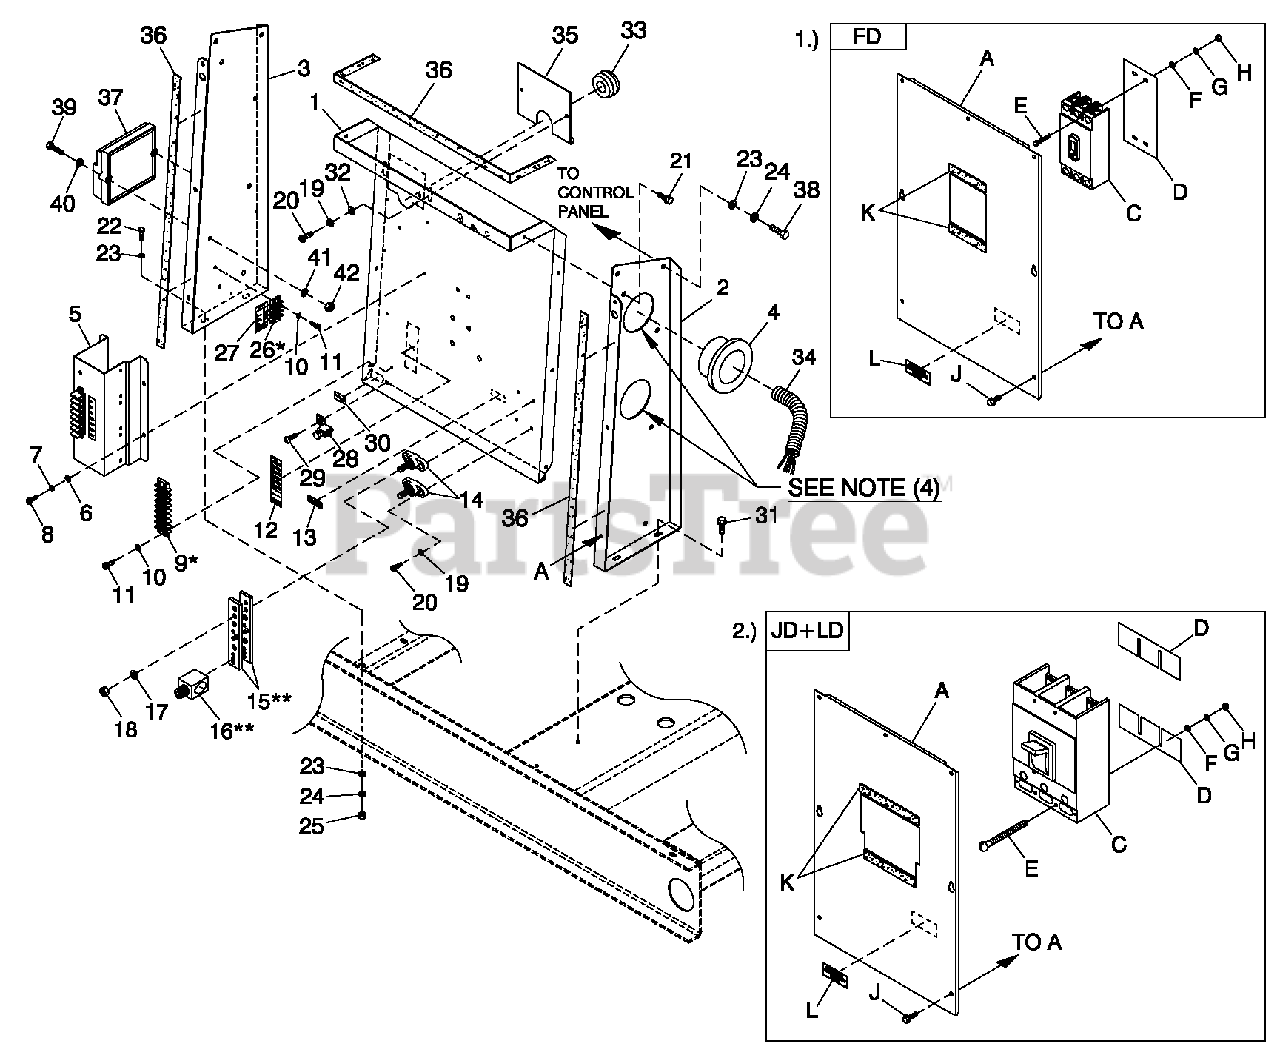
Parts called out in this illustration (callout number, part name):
1	PANEL CB CONN BOX
1	UL CIRCUIT BREAKER (FD)
2	STAND RH CONTROL
2	UL CIRCUIT BREAKER (JD+LD)
3	STAND LH CONTROL C5 GRBX
4	BUSHING SNAP SB-2.5-31
5	INTERFACE 1PH 240V
6	WASHER FLAT M4
7	WASHER LOCK #8-M4
8	SCREW PHTT M4-0.7 X 10ZYC
9	BLOCK TERM 20A 8 X 6 X 1100V
10	WASHER LOCK#6
11	SCREW PHTT #6-32 X 1/2 ZYC
12	DECAL CPL CUST CONN H CTRL
13	DECAL NEUTRAL
14	JUNCTION BLOCK 3/8-16
15	BUS BAR NEUTRAL BLOCK 390
16	LUG SLDLSS 600/250-1/0 X 1/4-28
17	WASHER LOCK 3/8
18	NUT HEX 3/8-16 STEEL
19	WASHER LOCK M5
20	SCREW PHTT M5-0.8X 16 ZYC
21	SCREW THF M6-1 X 16 N WAZ/JS
22	SCREW HHC M6-1.0X20G8.8
23	WASHER FLAT 1/4-M6 ZINC
24	WASHER LOCK M6-1/4
25	NUT HEX M6X1.0G8YELCHR
26	BLOCK TERM 20A 6 X 3 X 1100V
27	DECAL CUST CONN 120V UTILITY
28	LUG SLDLSS #6-14X 13/64CU
29	SCREW HHTT #10-32X3/8 CZ
30	DECAL GROUND LUG
31	SCREW HHTT M6-1.0X 16ZYC
32	WASHER FLAT M5
33	GROMMET 1.25 X .25 X .75
34	CONDUIT FLEX 2.0" ID
35	PLATE WIRE SNGLGALV
36	TAPE ELEC 1/2 FOAM (AS REQ'D)
37	ASSY PCB 4.6L IGNITION MODULE
38	SCREW HHC M6-1.0X 16 G8.8
39	SCREW PPHM #10/32X2
40	WASHER FLAT #10 ZINC
41	WASHER LOCK #10
42	NUT HEX #10-32 STEEL
A	COVER FDFRMCB
C	CB 0150A 3P 600V S FD6 LL
D	INSULATOR CB FD FRAME 30MIL
E	SCREW SHC 1/4-20 X 4 G8.8 NZ
F	WASHER FLAT 1/4-M6 ZINC
G	WASHER LOCK M6-1/4
H	NUT HEX 1/4-20 STEEL
J	SCREW THF M6-1 X 16 N WA Z/JS
K	TAPE ELEC 1 /2 FOAM (AS REQ'D)
L	DECAL CUSTOMER CONNECT INSIDE
A	COVER CIRBRKRJD/LD
C	CB 0300A 3P 600V S JD6LL
D	INSULATOR CIRCUIT BR. JD/LD
E	SCREW RHM 1/4-20X3
